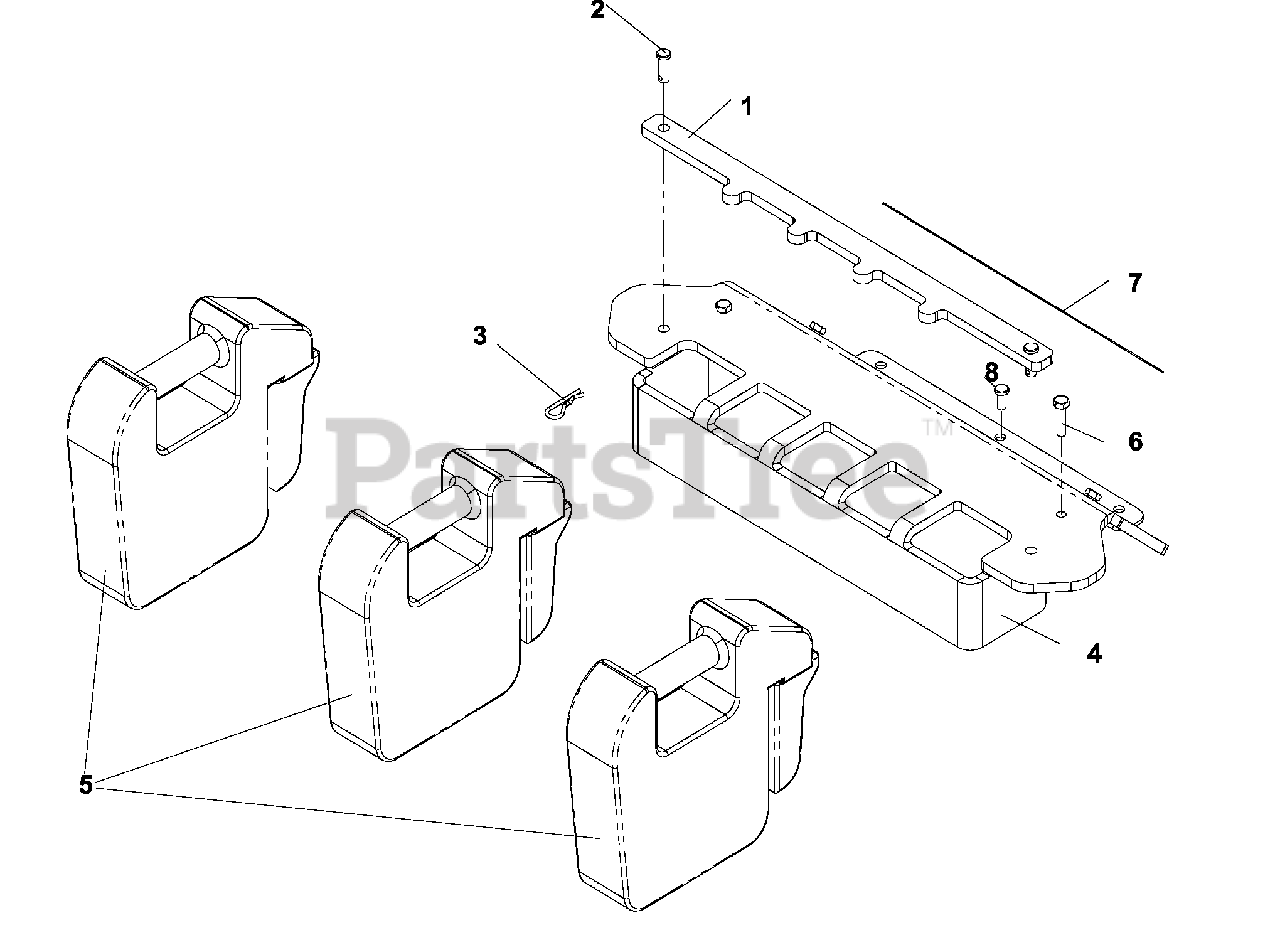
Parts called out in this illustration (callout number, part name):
1	HOLD DOWN, WEIGHT BAR
2	CLEVIS PIN
3	RETAINER SPRING
4	WEIGHT BAR
5	FRT WEIGHT CAST PZ DFS
6	HCS 5/16C X 1 1/4
7	ANTI-SKID PAD
8	GROMMET, BUMPER
